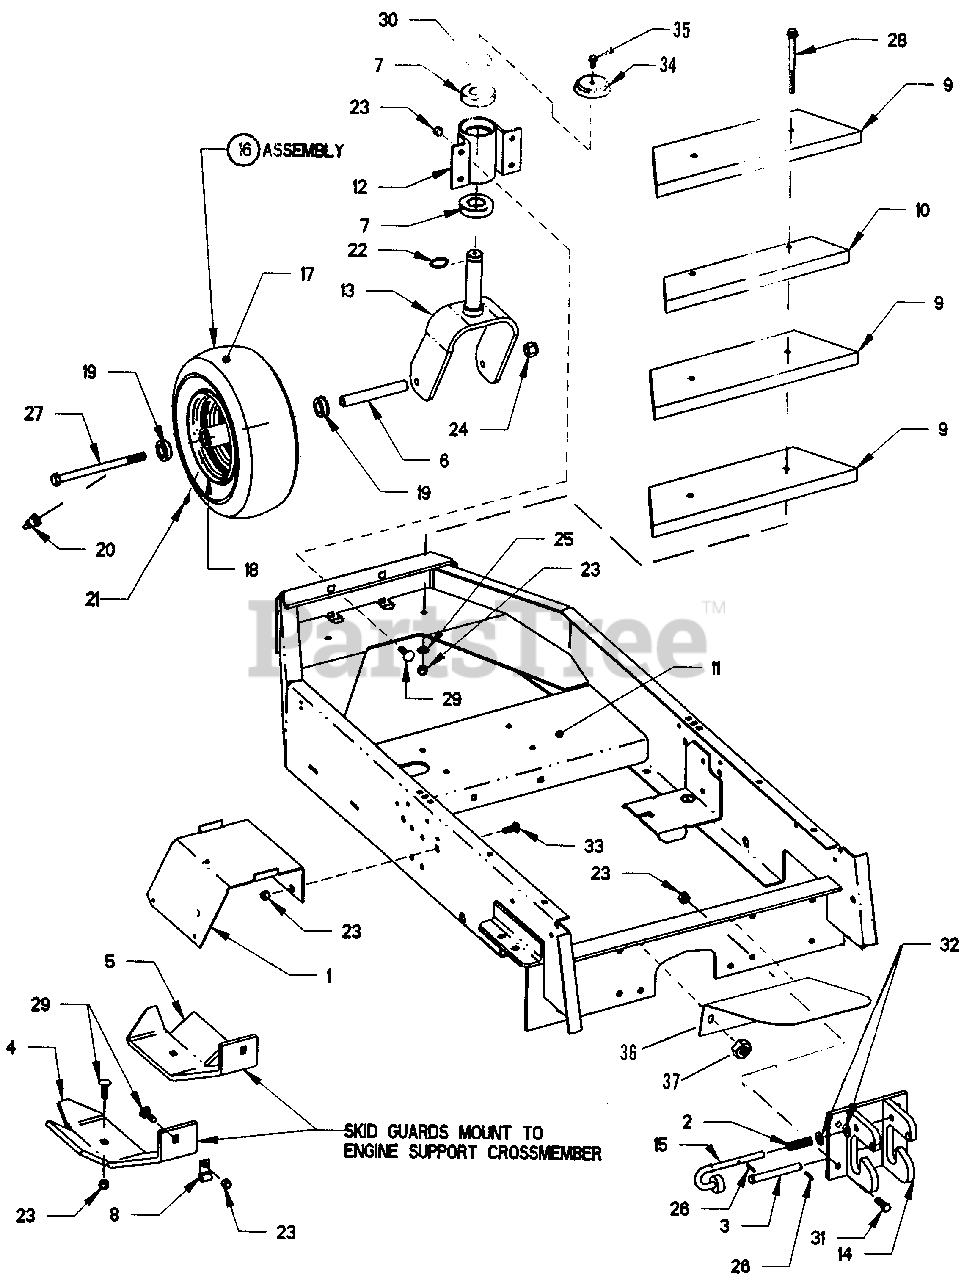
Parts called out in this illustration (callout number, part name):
1	BRACKET, Battery Support
2	SPRING
3	PIN, Clevis 1/2 x 4"
4	SKID GUARD, R.H.
5	SKID GUARD, L.H.
6	SLEEVE, Axle
7	BEARING, 30mm x 62mm
8	J-CLIP, Open Cushioned
9	COUNTERWEIGHT, Large
10	COUNTERWEIGHT, Small
11	CHASSIS, Lower
12	SUPPORT, Caster
13	YOKE, Caster
14	PLATE, Hitch
15	PIN, Hitch
16	ASSEMBLY, Tire & Rim
17	TIRE, 13 x 5.00-6 4 Ply
19	BEARING
20	VALVE, Air
21	FITTING, Lube
22	RING, 1-3/16" External Retaining
23	NUT, 3/8-16 HEX NYLON LOCK
24	NUT, 1/2-13 Nyloc
25	WASHER, 3/8" Flat
26	PIN, Cotter, 1/8 x 3/4"
27	BOLT, HEX, 1/2-13 X 7, GD 8, YZ
28	BOLT, 3/8-16 x 4-3/4", Grade 5
29	BOLT, 3/8-16 x 1-1/4", Carriage, Grade 5
30	WASHER, 1-1/4 I.D. x 1-7/8 O.D. Flat
31	BOLT, 3/8-16 X 1-1/4" GD5 CZ
32	WASHER, 15/32 I.D. x 15/16" O.D., Flat
33	BOLT, 3/8-16 x 1" Carriage, Grade 5
34	CAP, Caster Shaft
35	SCREW, 5/16-18 x 5/8" Self Tapping
36	SHIELD, Grass
37	NUT, 3/8-16 HEX NYLON LOCK
